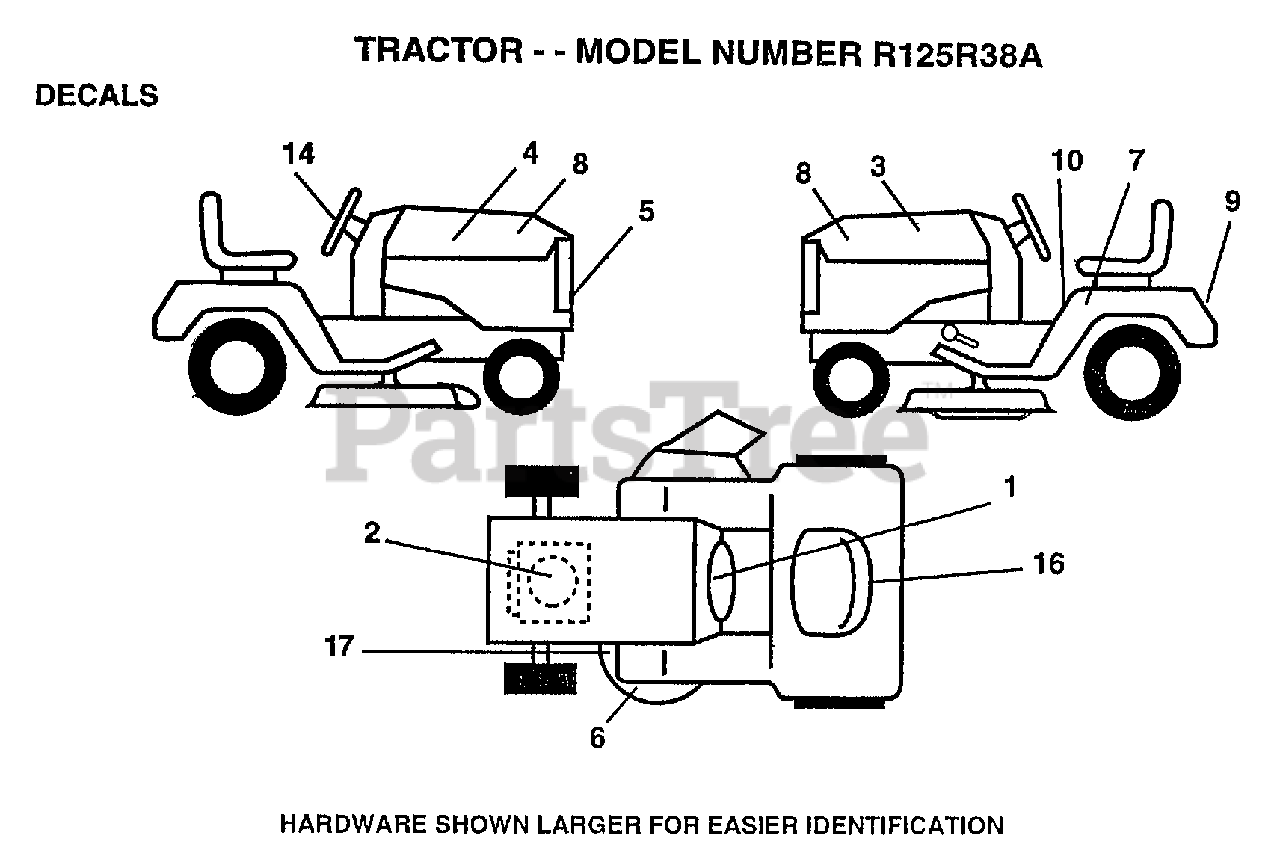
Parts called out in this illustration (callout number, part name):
1	DECAL.INST.OPER
2	DECAL, HP ENGINE
3	DECAL HD RLY LH
4	DECAL HD RLY RH
5	GRILL DECAL
7	IND HGT DECK DECA
8	DECAL.HOOD.12.5
9	FENDER DECAL
10	DECAL
14	"DECAL,STR WHL"
16	DECAL.BTRY.DANGER
17	DECAL
